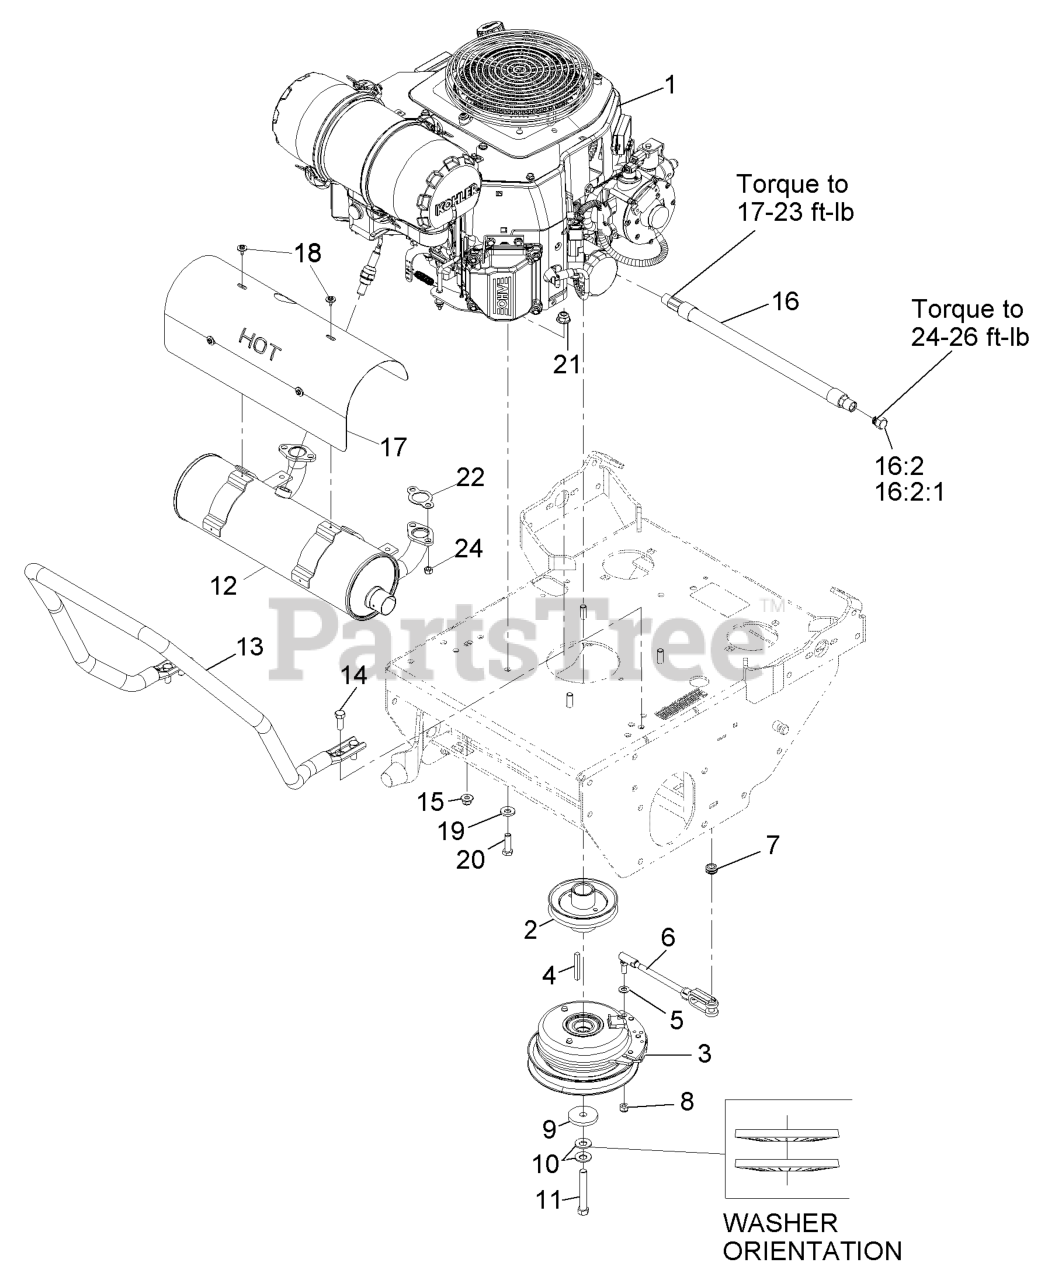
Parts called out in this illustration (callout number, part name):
2	SHEAVE, W/ HUB
3	CLUTCH, 125 FT/LBS, 1.13
4	KEY-SQUARE
5	WASHER-PLAIN
6	ASM, CLUTCH ANCHOR
7	GROMMET
8	NUT-LOCK
9	WASHER-CLUTCH
10	WASHER-SPRING
11	SCREW-HH
12	MUFFLER-TTX, EFI
13	GUARD,AIR CLEANER
14	SCREW-HH
15	NUT-HF, NI
16	OIL DRAIN HOSE ASM
16:2	PLUG-HH
16:2:1	O-RING
17	SHIELD-MUFFLER,TTX EFI
18	SCREW-HH, THREAD FORMING
19	WASHER-SPRING
20	SCREW-HH
21	NUT-HF, NI
22	GASKET-EXHAUST
